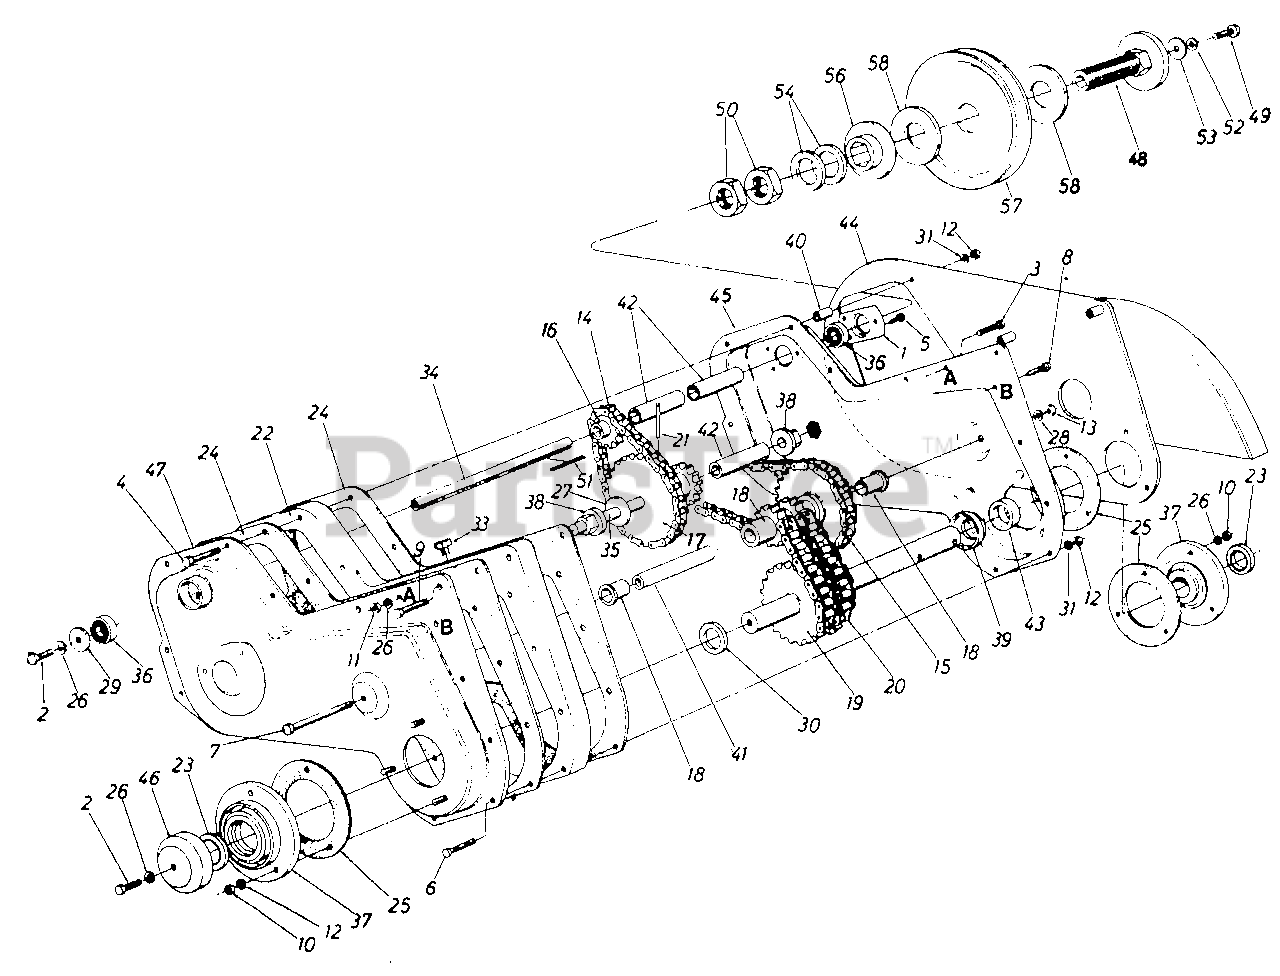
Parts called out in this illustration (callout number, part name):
1	Bearing Housing 1-3/8" Dia.
2	Hex Bolt 5/16-18 x .88" Lg. Spec.
3	Hex Bolt 5/16-18 x 1.50" Lg.*
4	Hex Bolt 1/4-20 x 2.75" Lg. *
5	Hex Wash. S-Tap. Scr. 1/4-20 x .50" Lg.
6	Hex Bolt 1/4-20 x 1.50" Lg.*
7	Hex Bolt 3/8-16 x 4.5" Lg.
8	Hex Wash. Hd. Bolt 1/4-20 x 1.5" Lg.
9	Hex Wasll. TT Tap Scr. 5/16-18 x 1.75" Lg.
10	Hex Cent. L.-Nut5/16-18 Thd.
11	Hex Nut 5/16-18 Thd.*
12	Hex Nut 1/4-2 Thd.*
13	Hex Nut 3/8-16 Thd.*
14	#41 Chain 1/2" Pitch x 34 Links-Endless
15	#42 Chain 1/2" Pitch x 48 Links-Endless
16	Sprocket 10 Tooth .500" Pitch
17	10 & 28 Teeth Sprocket Ass'y.
18	8-2 & 28 Sprocket Sleeve Ass'y
19	18-2 Sprocket Shaft Ass'y.
20	#50-2 Chain 5/8" Pitch x 28 Links-Endless
21	Spring Pin Spir. 1/4" Dia. x 1.50" Lg.
22	Spacer Block-Tiller Housing
23	Oil Seal Double Lip-1-1/4" Dia.
24	Gasket for Tiller Housing
25	Gasket for Brg.-Housing
26	L.-Wash. 5/16" I.D.*
27	Fl.-Wash. .640" I.D. x 1.24" O.D.
28	L.-Wash. 3/8" I.D. Heavy Duty
29	Fl.-Wash. .344" I.D. x.1.125"
30	Special Washer
31	L.-Wash. 1/4" I.D.*
33	Vent Plug
34	Jack Shaft .525" I.D. x 7.78" Lg.
35	Sprocket Shaft .63" Dia. x 5.0" Lg.
36	Ball Brg. .62" I.D. x 1.38" O.D.
37	Bearing Housing-1 1/4"
38	Hex Flange Brg.
39	Spacer 1.25" I.D. x 2.0" O.D.
40	Spacer.28" I.D. x .62" O.D. x .90" Lg.
41	Spacer.38" I.D. x.62" O.D. x 3.44" Lg.
42	Spacer.62" I.D. x .88" O.D. x 1.56" Lg.
43	Spacer 1.25" I.D. x 1.62" O.D. x.50" Lg.
46	Dust Cap .320" Dia. Hole
49	Hex Bolt 5/16-18 x 1.25" Lg. Grade 5
50	Hex Jam Nut 1.0-14 x 28 Thd.
51	Sq. Key 3/16 x 1.50" Lg.
52	L.-Wash. 5/16" I.D.*
53	Fl.-Wash. .344" I.D. x 1.125" 0.D.
54	Spring Bell Wash. 1.0" I.D. x 2.0" O.D.
56	Floating Disc 3-1/4" O.D. x 1.0" I.D.
57	5/8 V-Pulley 1.50" I.D. x 6.50"
58	Friction Pad 3-1/4" O.D. x 1-3/8" I.D.
